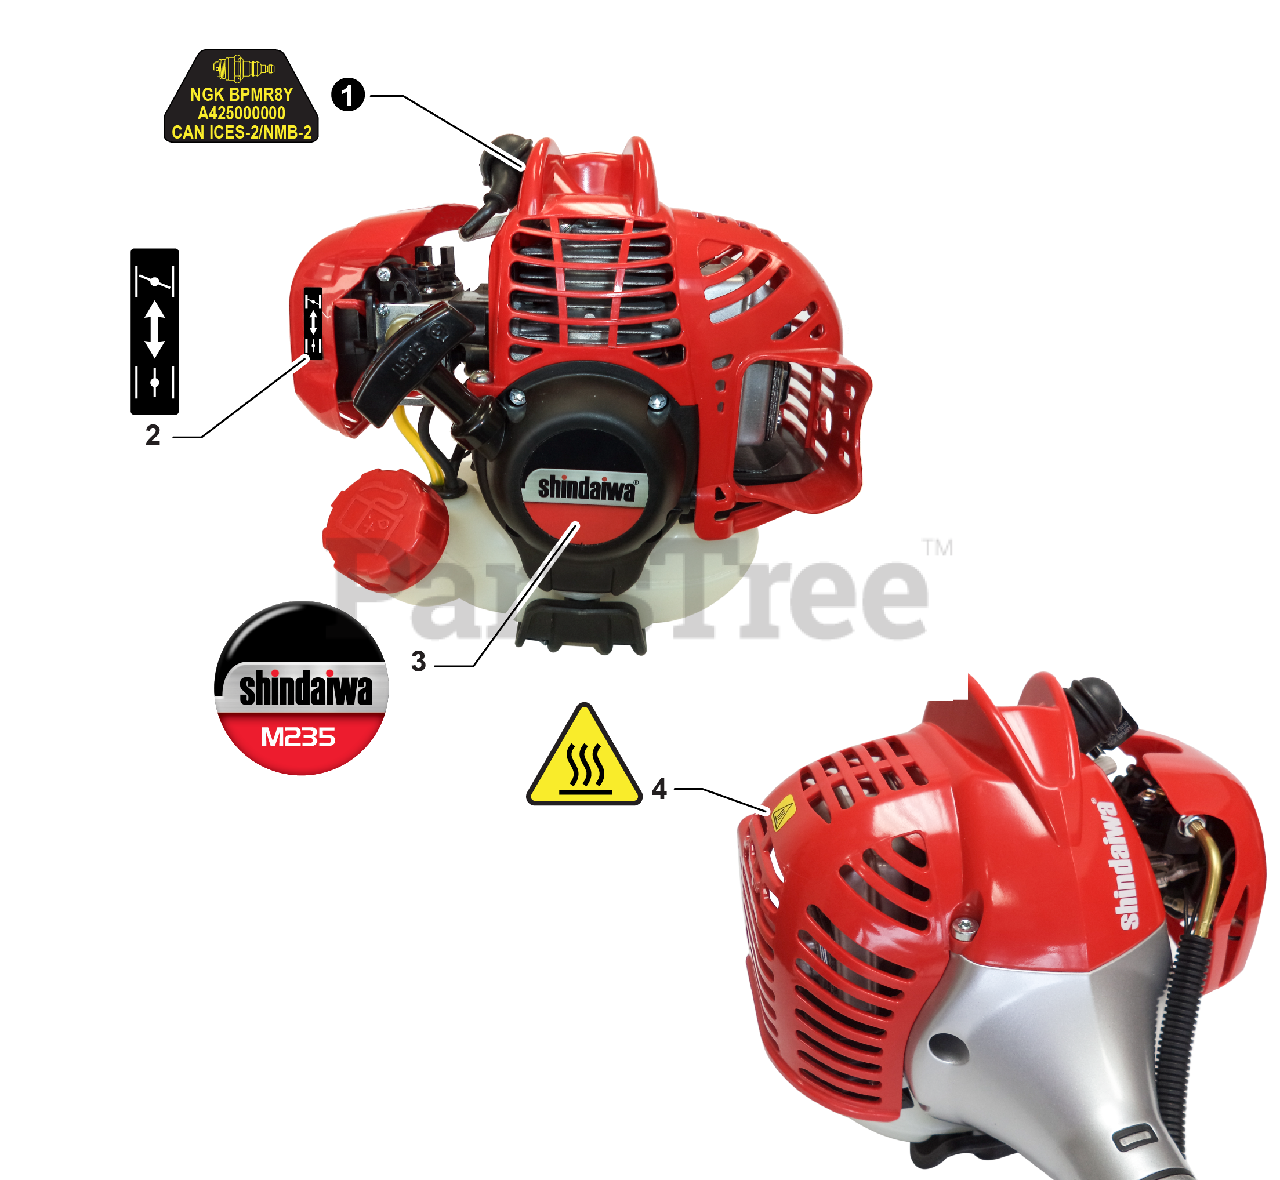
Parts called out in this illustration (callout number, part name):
1	LABEL - SPARK PLUG - BPMR8Y
2	LABEL - CHOKE
3	LABEL - SHINDAIWA - M235
4	LABEL - CAUTION - HOT
